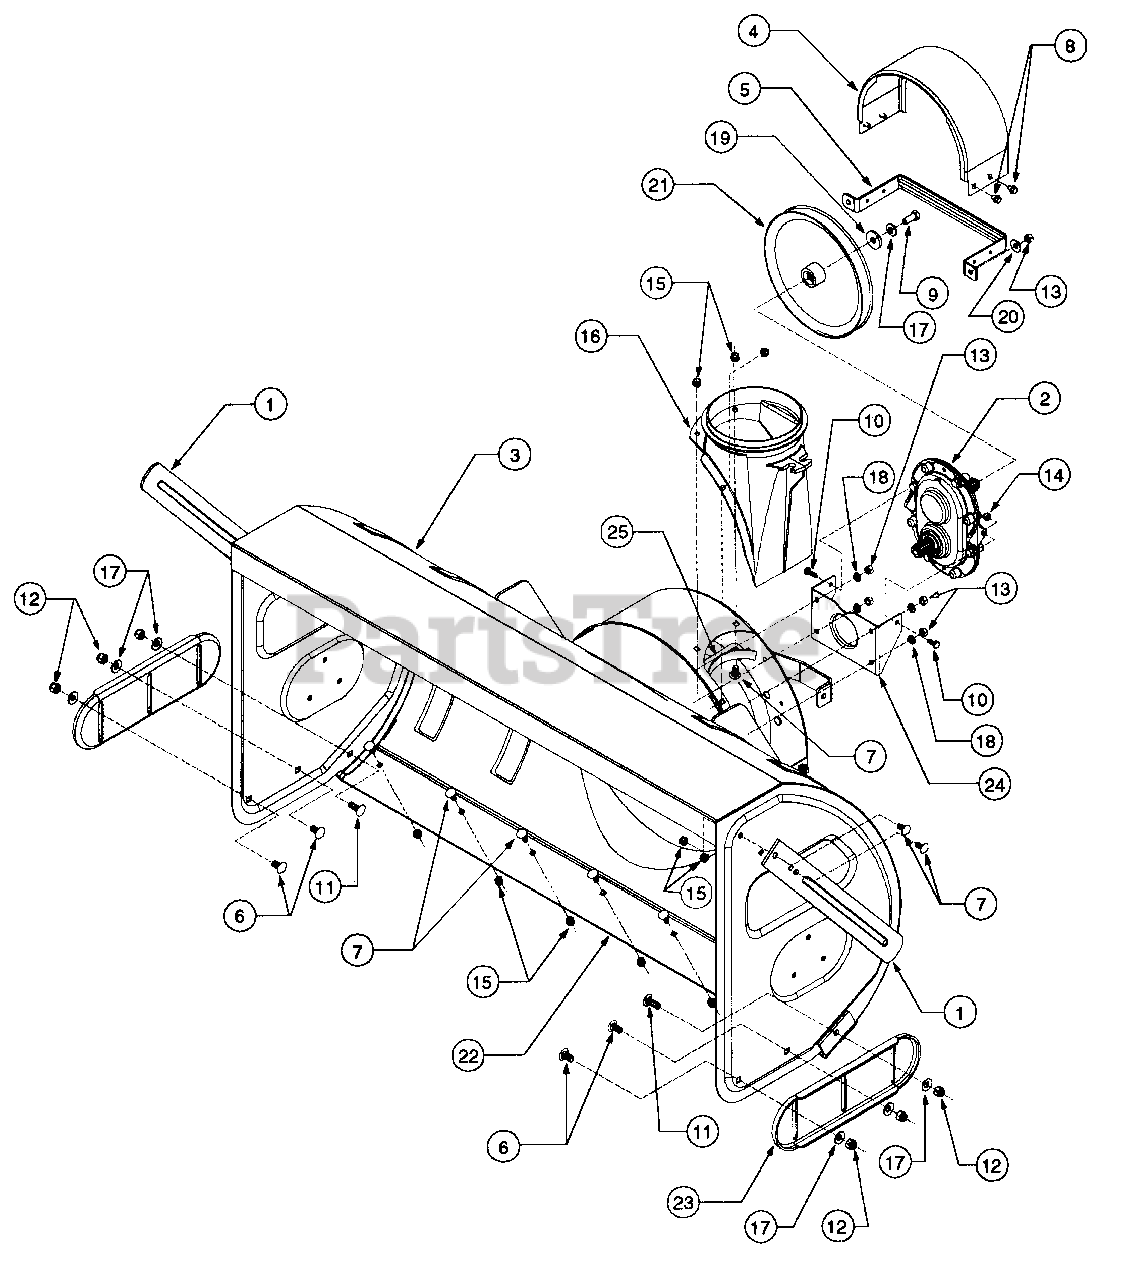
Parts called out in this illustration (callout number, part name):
2	Gear Box Ass'y
7	Bolt, Carriage, 5/16-18 X .75
8	Screw, Hex Wash. Hd. Tapp 1/4-20 X .375
9	Screw, Hex Cap, 3/8-24 X .875 GR8.
10	Screw, Hex Cap, 1/4-20 X .75 GR5
11	Bolt, Carriage, 3/8-16 X 1.0 GR5
12	Nut, Hex Insert Lock, 3/8-16
13	Nut, Hex, 5/16-18
14	Nut, Hex Insert Lock, 1/4-20
15	Nut, hex Insert Lock, 5/16-18
16	Adapter, Discharge Chute
17	Washer, Bell, .401 X .870 X .063 Thk
18	Washer, Lock, 5/16
19	Washer, Flat, 3/8 X 1.26 X .172 Thk
20	Washer, Bell, .345 X .88 X .06 Thk
